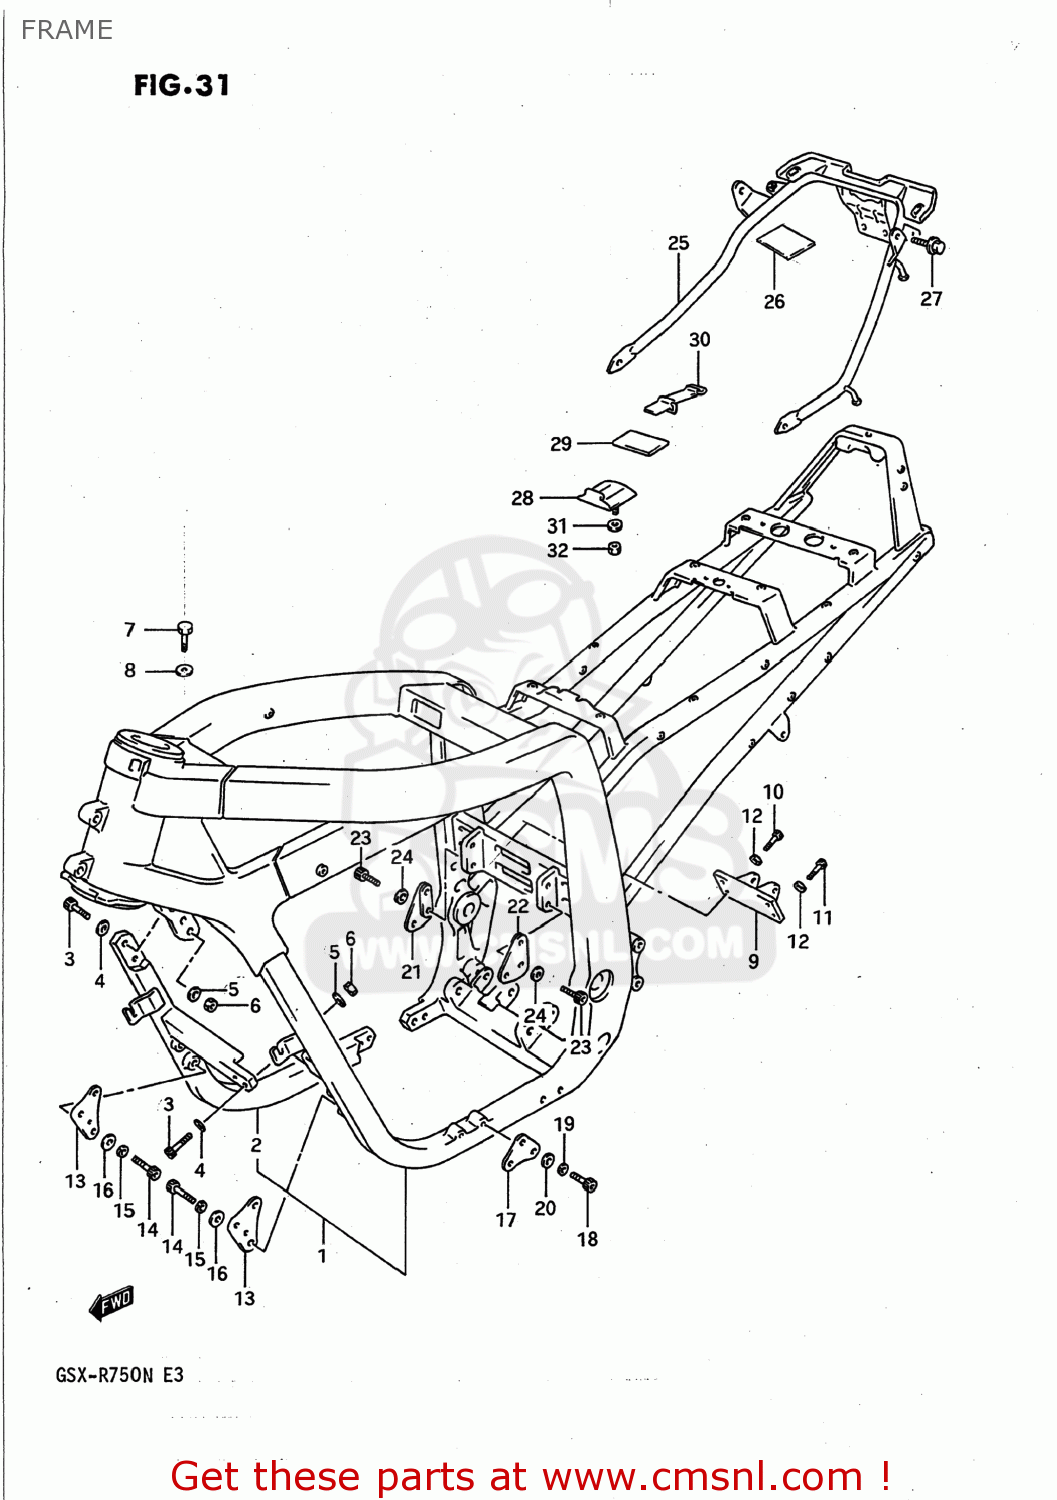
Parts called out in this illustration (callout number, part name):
1	1-2
2	TUBE,FRAME
3	BOLT, LH
4	WASHER (10.1X21X2.3)
5	WASHER
6	NUT
7	BOLT
8	GASKET(6.2X11X1) (NAS)
9	BRACKET,RCU
10	BOLT 10X27
11	BOLT, LH
12	WASHER
13	PLATE,ENGINE MOUNTING
14	BOLT, FRONT LH
15	WASHER,LOCK
16	WASHER (8.2X20X1.6)
17	PLATE,ENGINE MOUNT NO.2
18	BOLT, FRONT LH
19	WASHER,LOCK
20	WASHER (8.2X20X1.6)
21	PLATE,ENGINE MOUNT NO.3,R
22	PLATE,ENGINE MOUNTING NO
23	BOLT(8X22)
24	WASHER (8.2X20X1.6)
25	GRIP,RR
26	TAPE,FRAME PROTECTOR
27	BOLT
28	HOLDER,TOOL
29	CUSHION
30	BAND
31	WASHER
32	NUT 6MM
